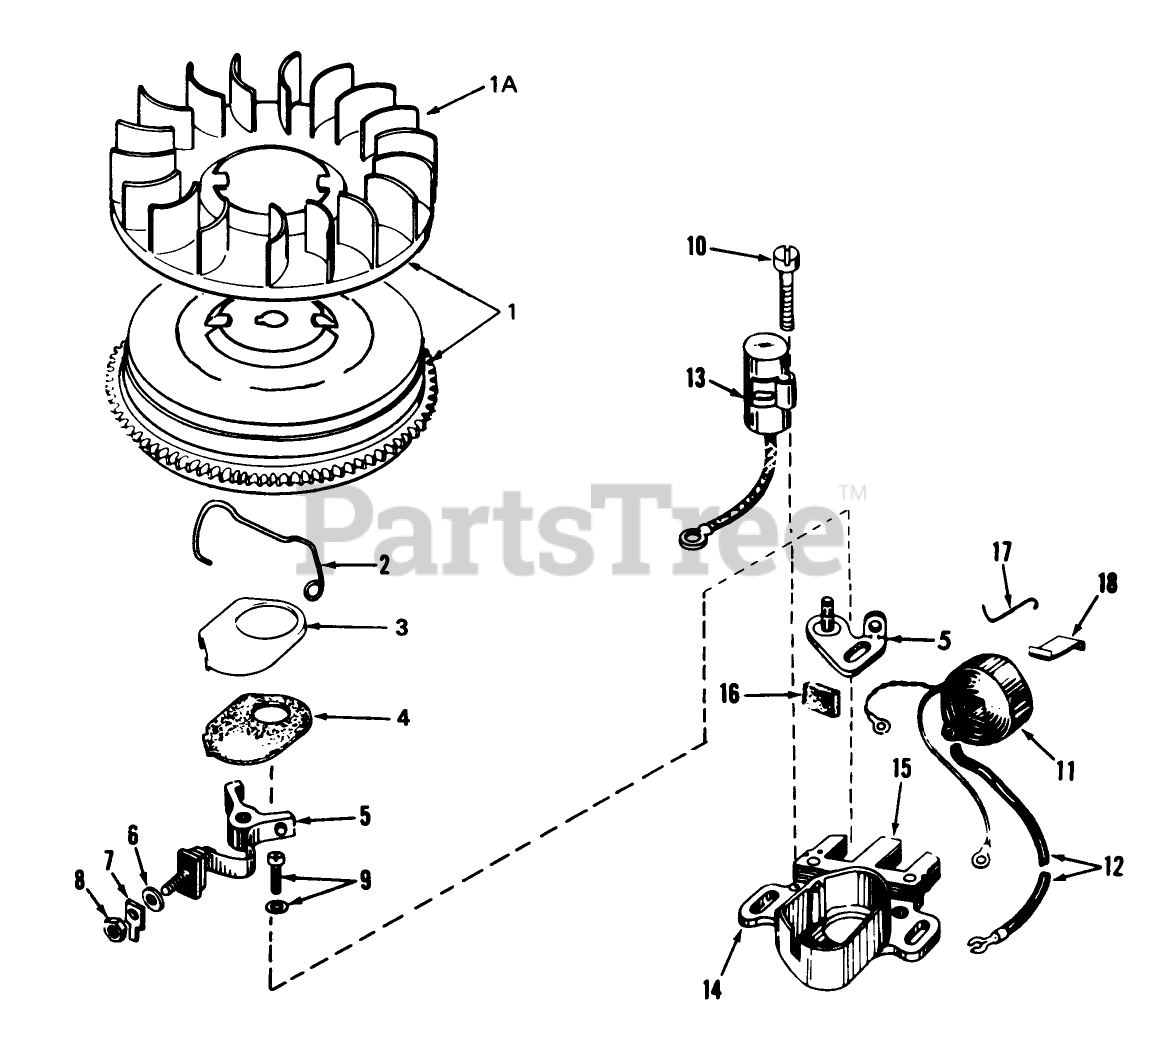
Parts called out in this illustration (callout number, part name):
1	5247/7229/68/R7268/
1A	Fan
2	Spring Breaker Box
3	Cover-Dust
4	Gasket, Dust Cover
5	Breaker Assy.
6	Washer
7	Terminal, Ground
8	DECAL
9	Breaker Screw
10	Condenser Screw
11	Coil Assy. (Incl. No. 12)
12	Wire, Lead
13	Condenser
14	Core Plate
15	Stator Assy. (Incl. Ref. #2 thru 11, 13, 14, 16, 17 19)
16	Felt,Cam Wiper
17	Clip, Coil
18	Spring Coil Wedge
